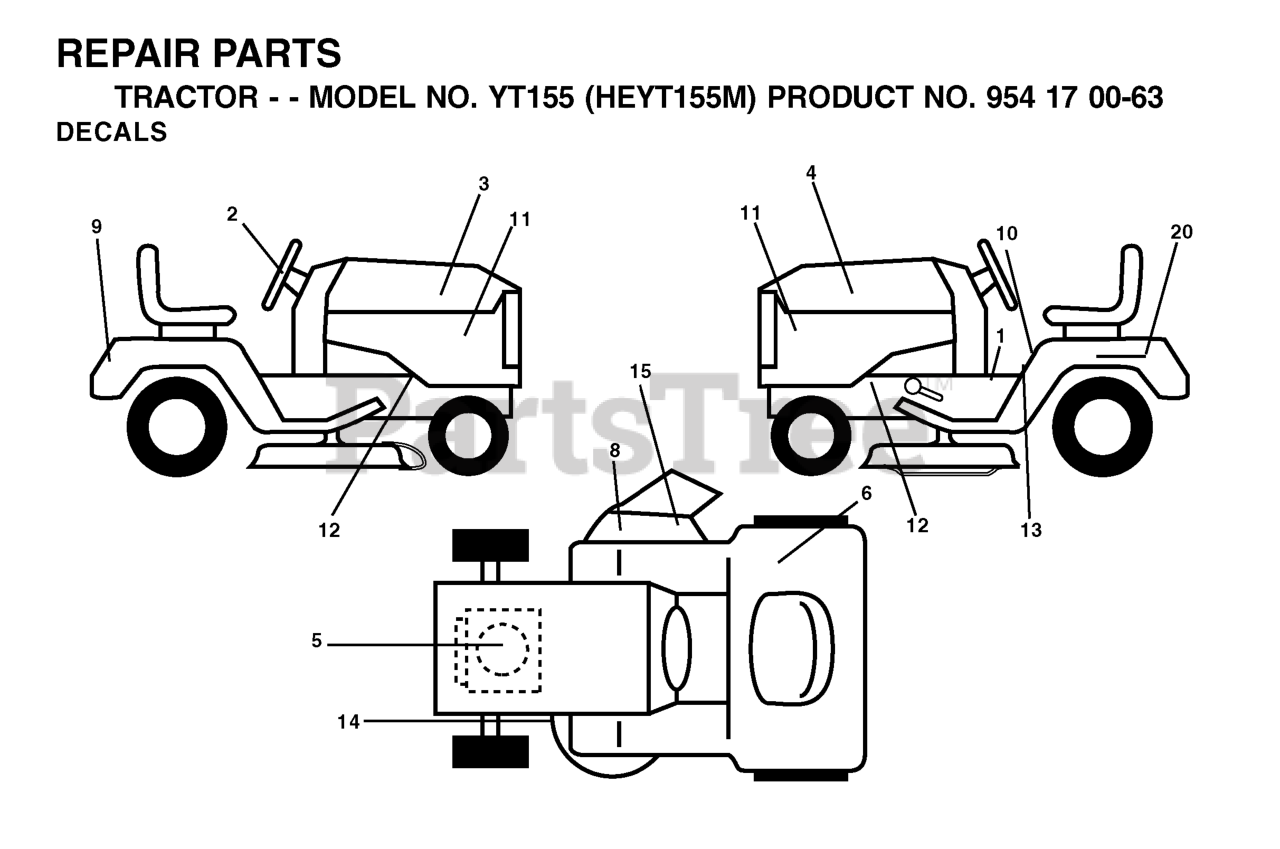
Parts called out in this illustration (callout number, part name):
1	DECAL PARK BRAKE
2	DECAL.WHEEL.STEERING.HUSQ.PERM
6	Decal, Fender 100 DB/CE
8	DECAL.INTERNATIONL.CUTFINGER
9	DECAL FENDER HUSQ
10	DECAL READ OWNER'S MAN SYMS
11	DECAL PNL SIDE
13	DECAL
14	DECAL V BELT SCHEMATIC
15	DECAL DECK "B" 42"
20	DECAL BTRY SYMBOLS
